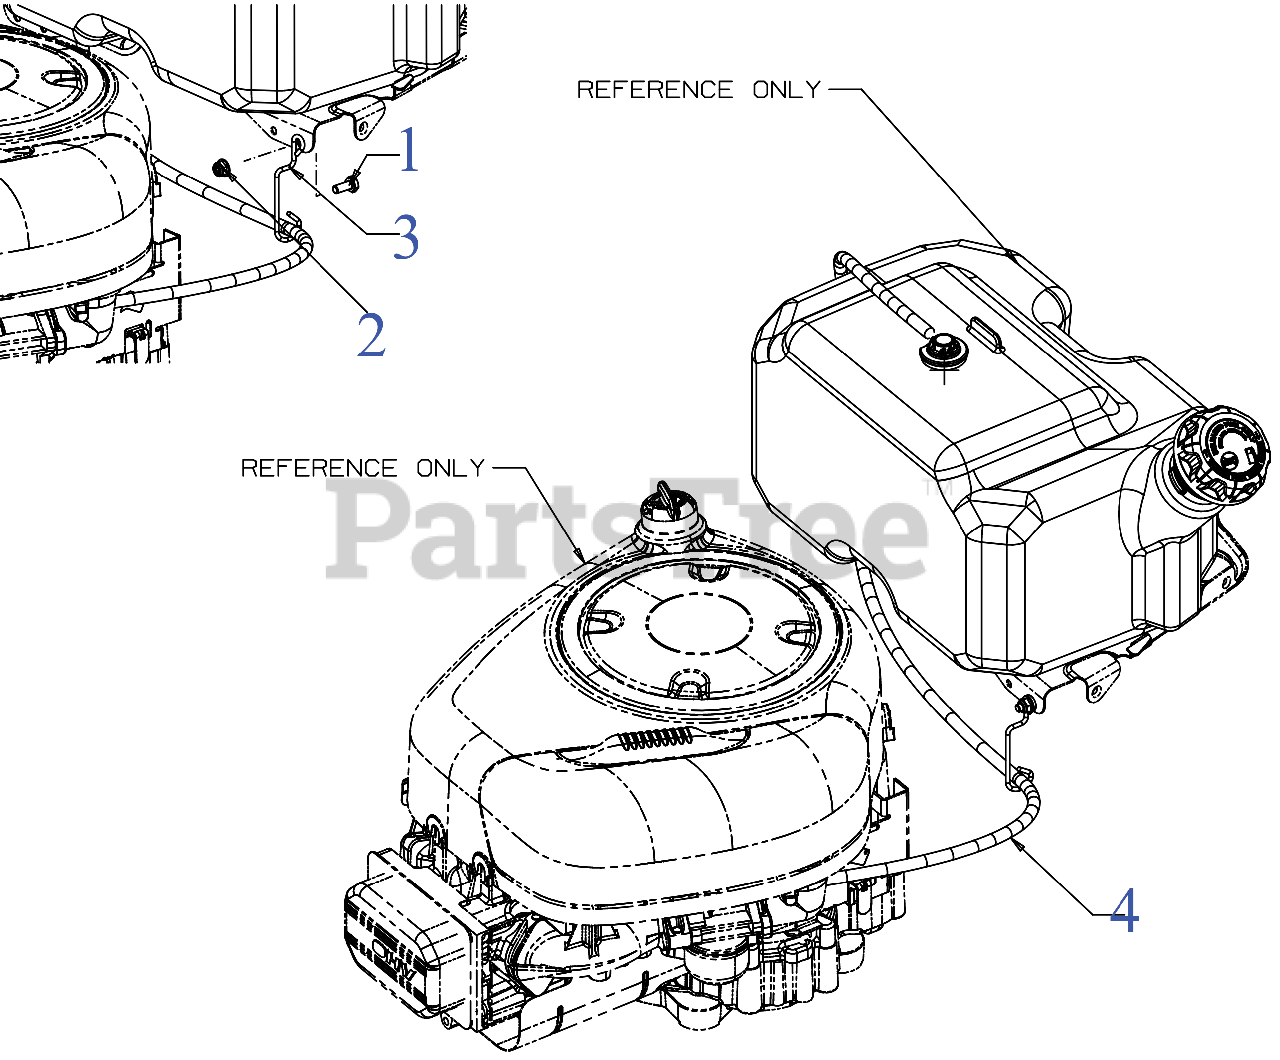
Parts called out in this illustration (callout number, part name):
1	SCREW 1/4-20 x .620 GR5
2	FLANGE LOCK NUT
3	CABLE GUIDE WIRE
4	VENT HOSE 3/16 ID 34"LG
